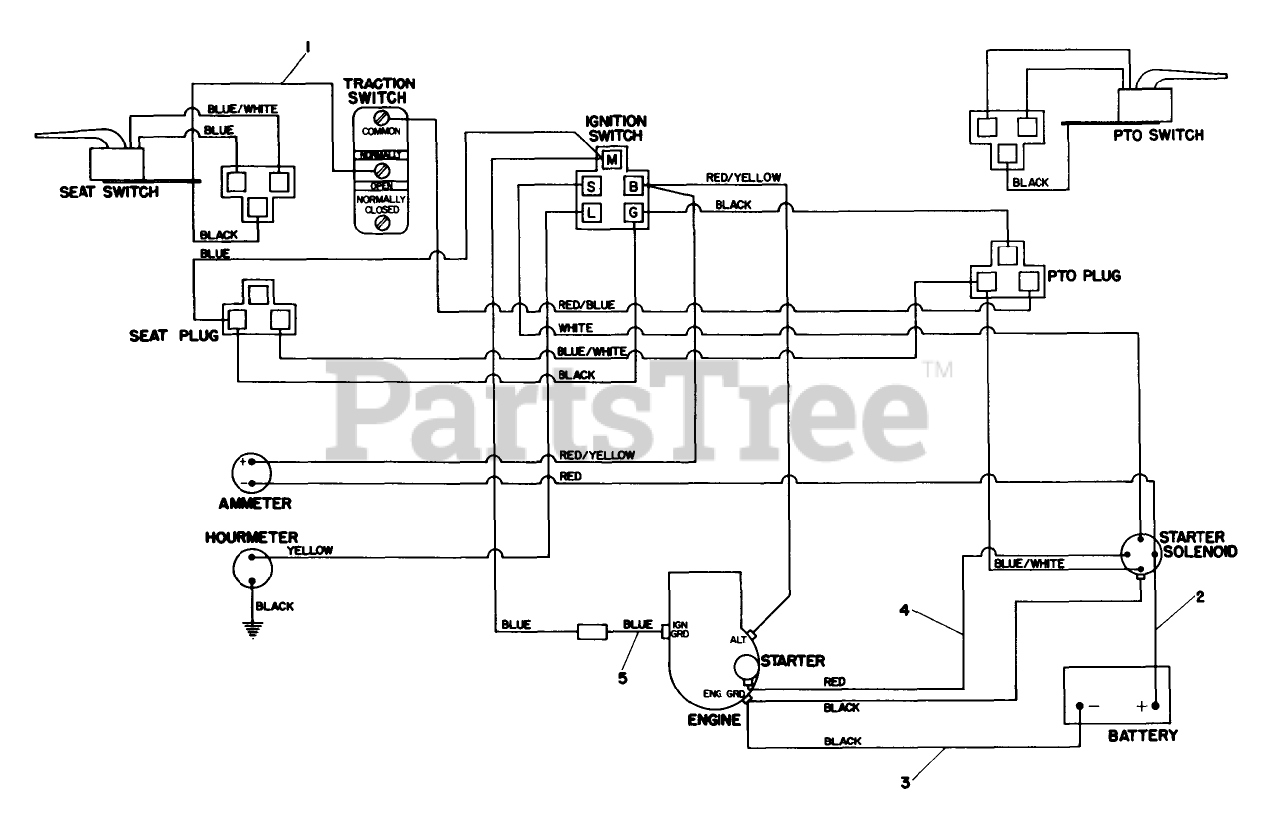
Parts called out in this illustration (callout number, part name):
1	Wire Harness
2	Wire Positive Batter to Solenoid
3	BATTERY GROUND WIRE
4	SOLENOID TO START WIR
5	ENGINE GROUND WIRE
